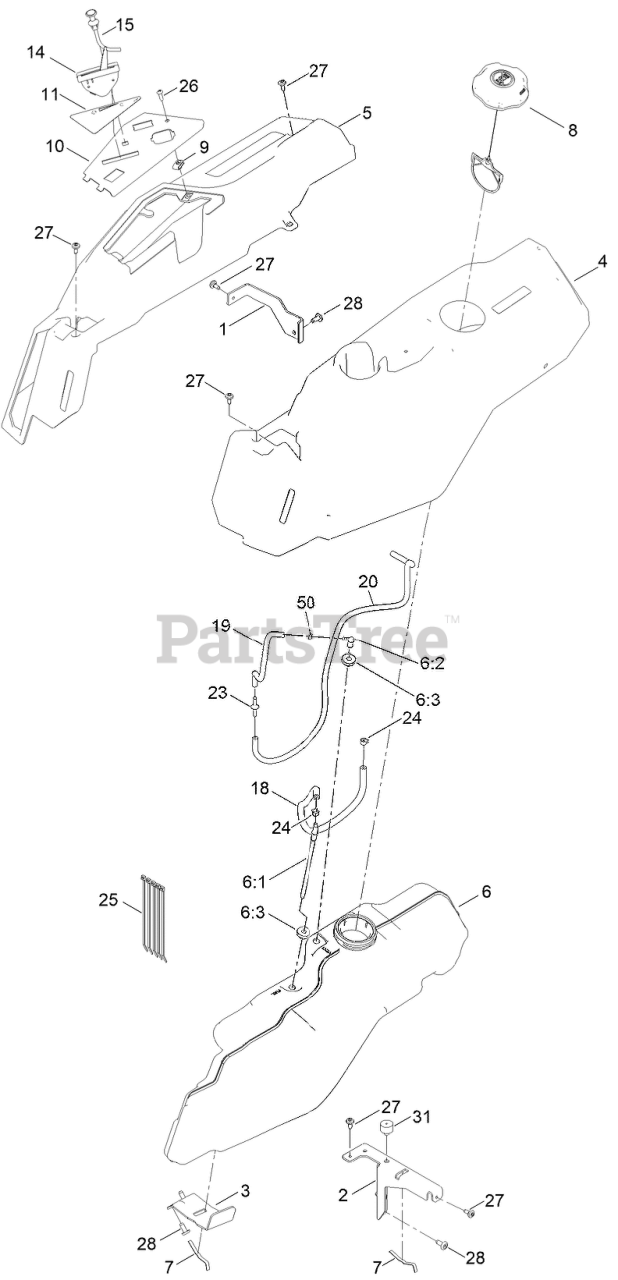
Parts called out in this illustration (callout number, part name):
1	BRACKET-POD
2	SUPPORT-POD, LH
3	SUPPORT-TANK, FUEL
4	POD-LH
5	POD-RH, MYRIDE
6	TANK-FUEL ASM
6:1	CONNECTOR-ELBOW, 90 DEG
6:2	FITTING-ELBOW 90
6:3	BUSHING
7	SPRING
8	CAP-FUEL, RATCHETING
10	PANEL - CONTROL
11	DECAL-PANEL, CONTROL
14	CABLE-THROTTLE
15	CABLE-CHOKE
18	HOSE-FUEL
19	HOSE-FUEL
20	HOSE-FUEL
23	ADAPTER ORIFICE
24	CLAMP-HOSE
25	TIE-CABLE
26	SCREW-PRH
27	SCREW-SHOULDER
31	BUMPER-GROMMET
50	CLAMP-HOSE
